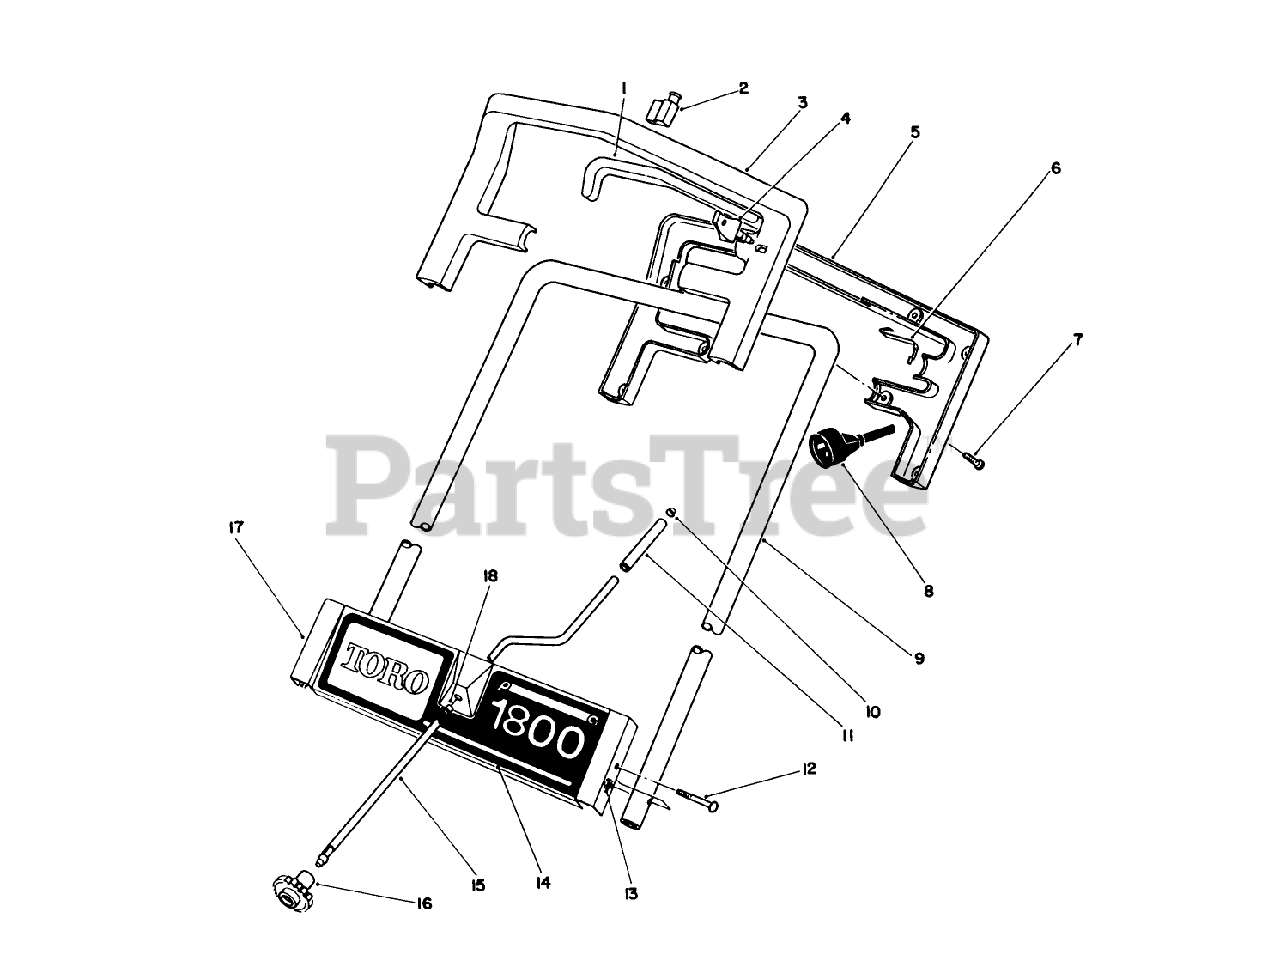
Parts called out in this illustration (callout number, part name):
1	CHUTE-DEFLECTOR
2	WASHER-FLAT
3	NUT-LOCK, NI
4	MIDDLE HANDLE - 1800
6	WASHER-RUBBER
7	LOWER CHUTE, 1800
8	SCREW-CARR
9	TUBE-UPPER HANDLE
10	PUSHNUT-CAP, WASHER
11	SLEEVE, CHUTE CRANK
12	SCREW-HH
13	NUT-LOCK, NI
15	ROD, CHUTE CRANK
16	GEAR-CHUTE CRANK
18	NYLINER
